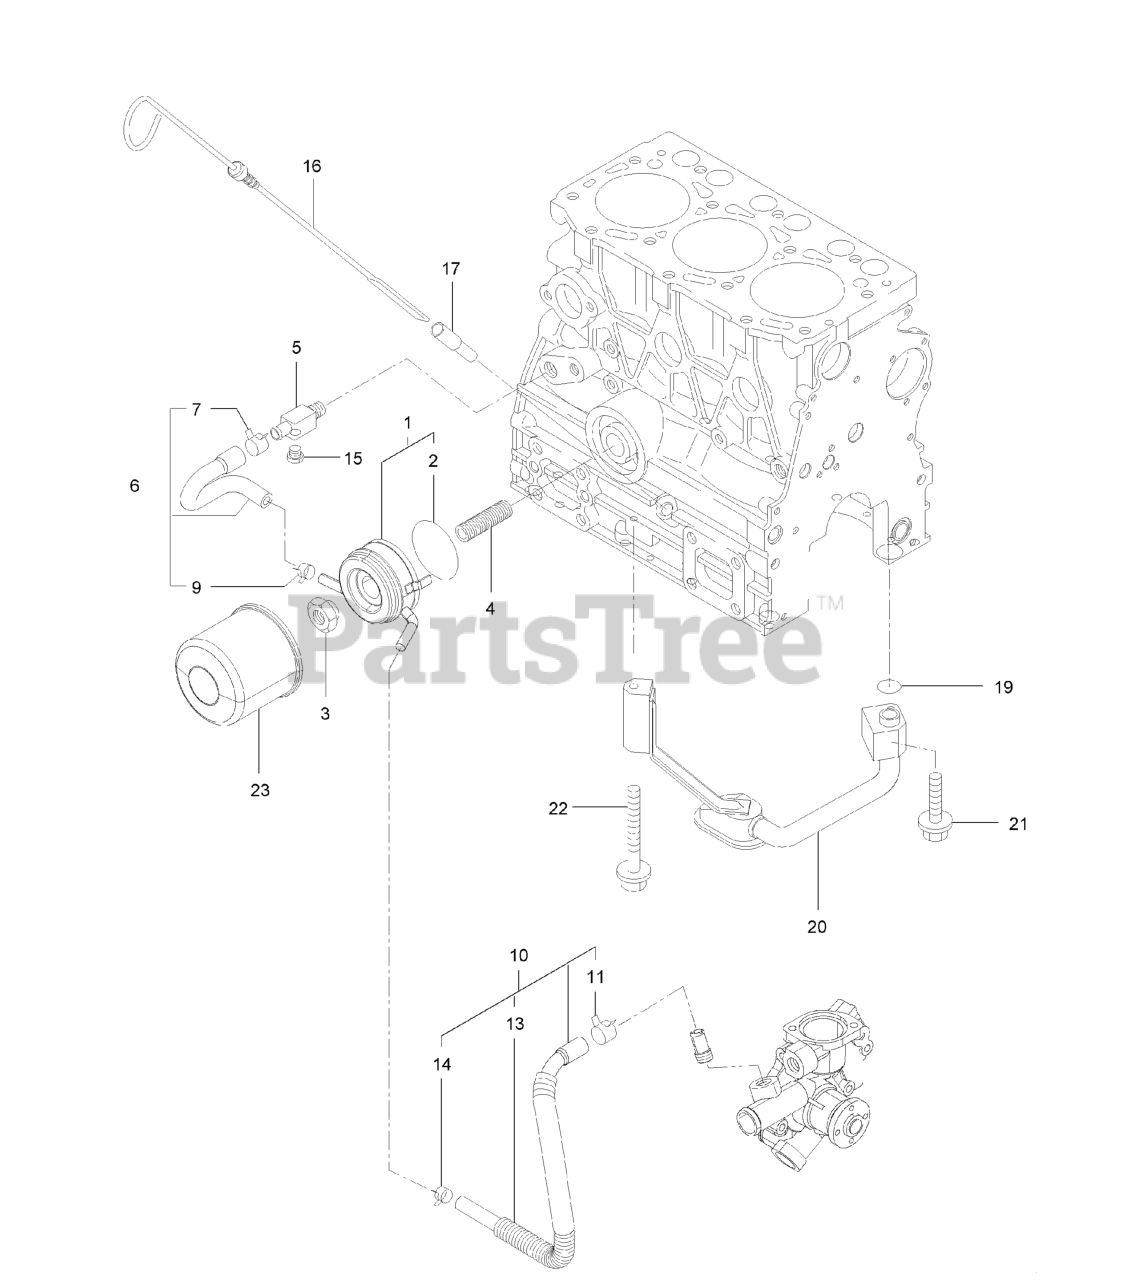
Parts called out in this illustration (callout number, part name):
1	COOLER-OIL
3	NUT-COOLER, OIL
4	STUD-LO FILTER
6	PIPE ASM-COOLER IN
9	CLAMP-HOSE
10	PIPE ASM
14	CLAMP-HOSE
15	PLUG-DRAIN
16	DIPSTICK
17	GUIDE-DIPSTICK
20	PIPE ASM-OIL INLET
23	FILTER ENGINE OIL
